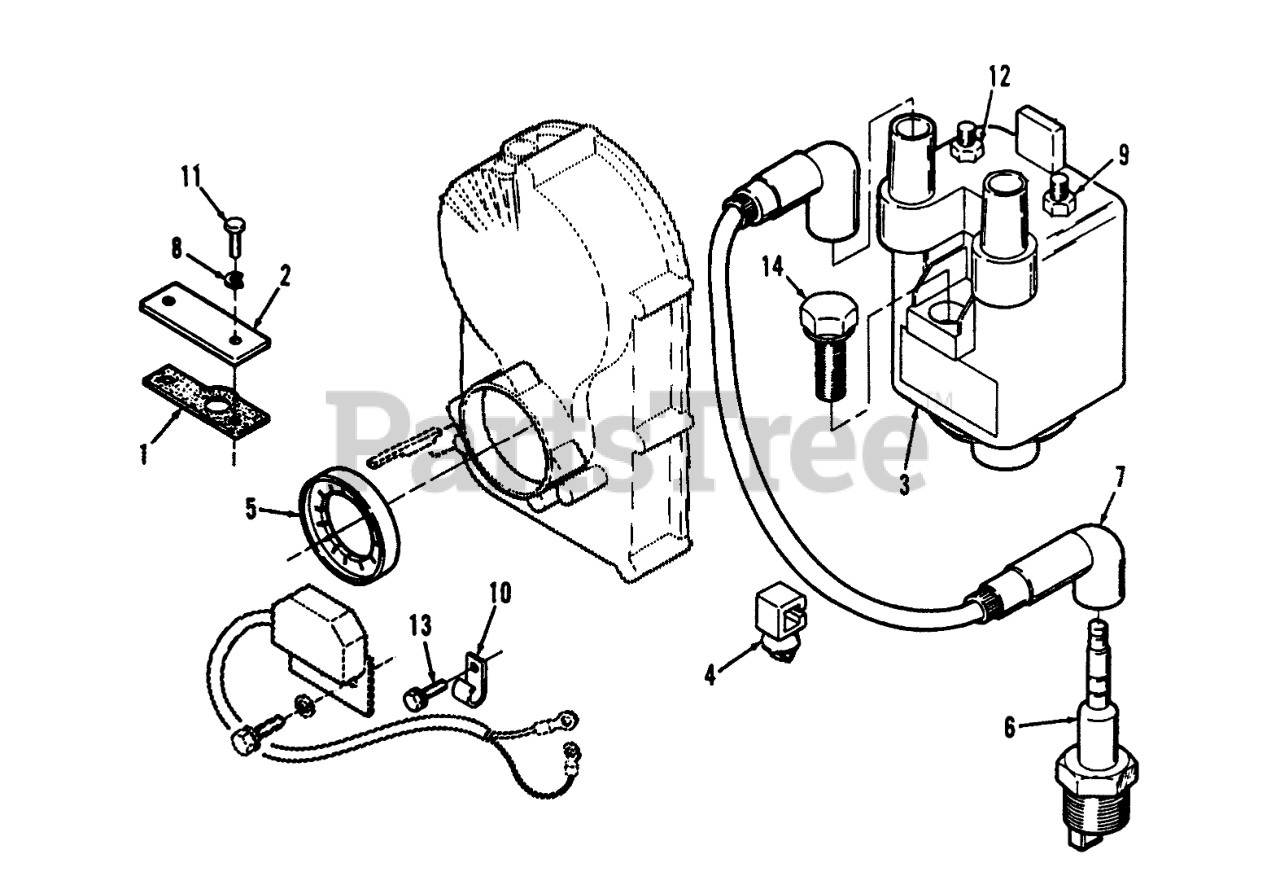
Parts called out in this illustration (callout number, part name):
1	Gasket-Plate
2	Plate
3	Coil-Battery Ignition(Includes Nuts)
4	Clip
5	Rotor
6	Plug-Spark
7	Wire-Plug
8	WASHER-FLAT
9	Nut
10	Clip
11	SCREW - CAP HEX HEAD
12	Nut
13	Bolt
14	Bolt
